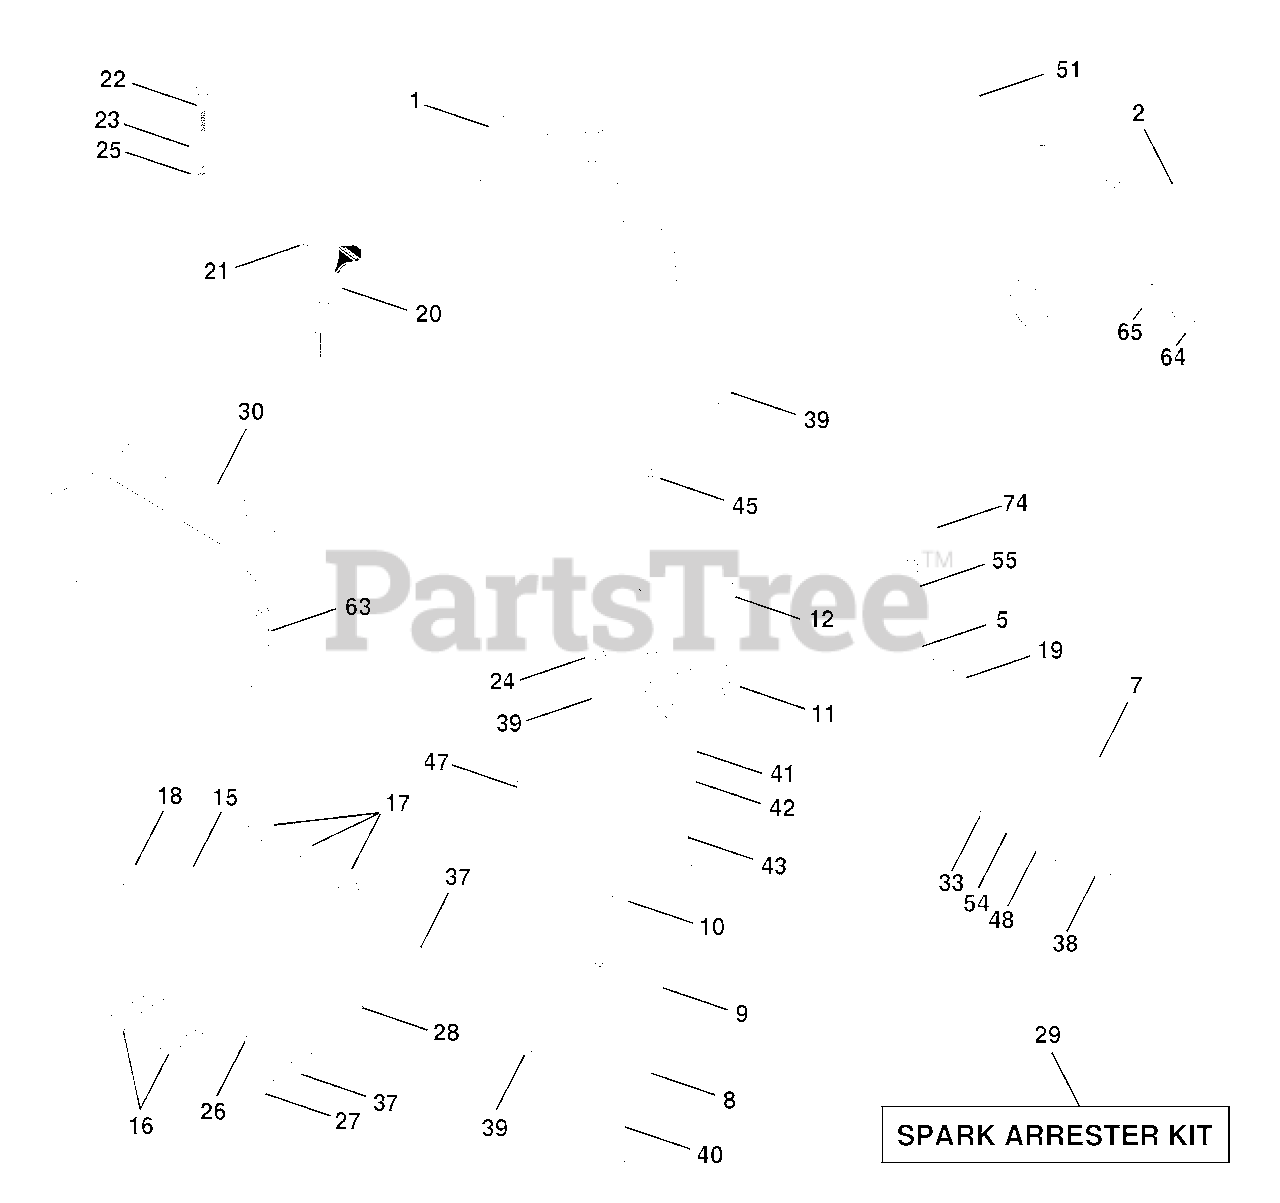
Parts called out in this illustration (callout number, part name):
1	Engine Kohler
2	Muffler Side 1-1/8"
5	Elbow STD 90 Degree 3/8-18 NPT
7	Muffler Assembly Guard
8	Pulley V-Idler
9	Keeper Asm Belt Engine VGT 96
11	Clutch Electric
12	Pulley Engine VGT Elect Clutch
15	Tank Fuel Rear
16	Pad Spacer
17	Pad Spacer
18	Cap Asm Fuel W/Sym Vented
19	Plug Oil Drain
20	Control Throttle
21	Screw Hex Thd Cut 1/4-20 X 5/8
22	Control Choke
23	Washer 13/32 X 13/16 x 16 Ga
24	Washer Ext Tooth 3/8
25	Nut Keps 3/8 - 24 UNF
26	Bushing
27	Stem Tank Fuel
28	Fuel Line
29	Spark Arrester Kit
30	Strip Foam 18"
33	Nut, Hex W/Ins. 3/8-16 UNC
37	Clamp Hose
38	Bolt, Fin Hex 3/8-16 UNC x 1-1/2
39	Screw TT 3/8-16 x 2-1/4 UNC
40	Screw TT 3/8-16 x 4 UNC
41	Washer 1-1/2 OD X 15/32 ID X .250
42	Washer Lock 7/16
43	Bolt Hex 7/16-20 X 4-1/4 Ga 5
45	Nut Flange 1/4-20 Starter Nut
47	Spacer Engine
48	Washer 13/32 x 1-1/4 x 7 Ga.
51	Manifold Pipe VGT CV 1-1/8
54	Washer Flat 13/32 x 7/8 x 14 Ga.
55	Nipple, Pipe 4-1/2"
63	Shield, Heat VGT YP/Husq.
64	Screw Thrdrol 3/8-16 x 3/4 Ty-TT
65	Washer 13/32 x 1 x 14 Ga.
74	Elbow Street Brass
